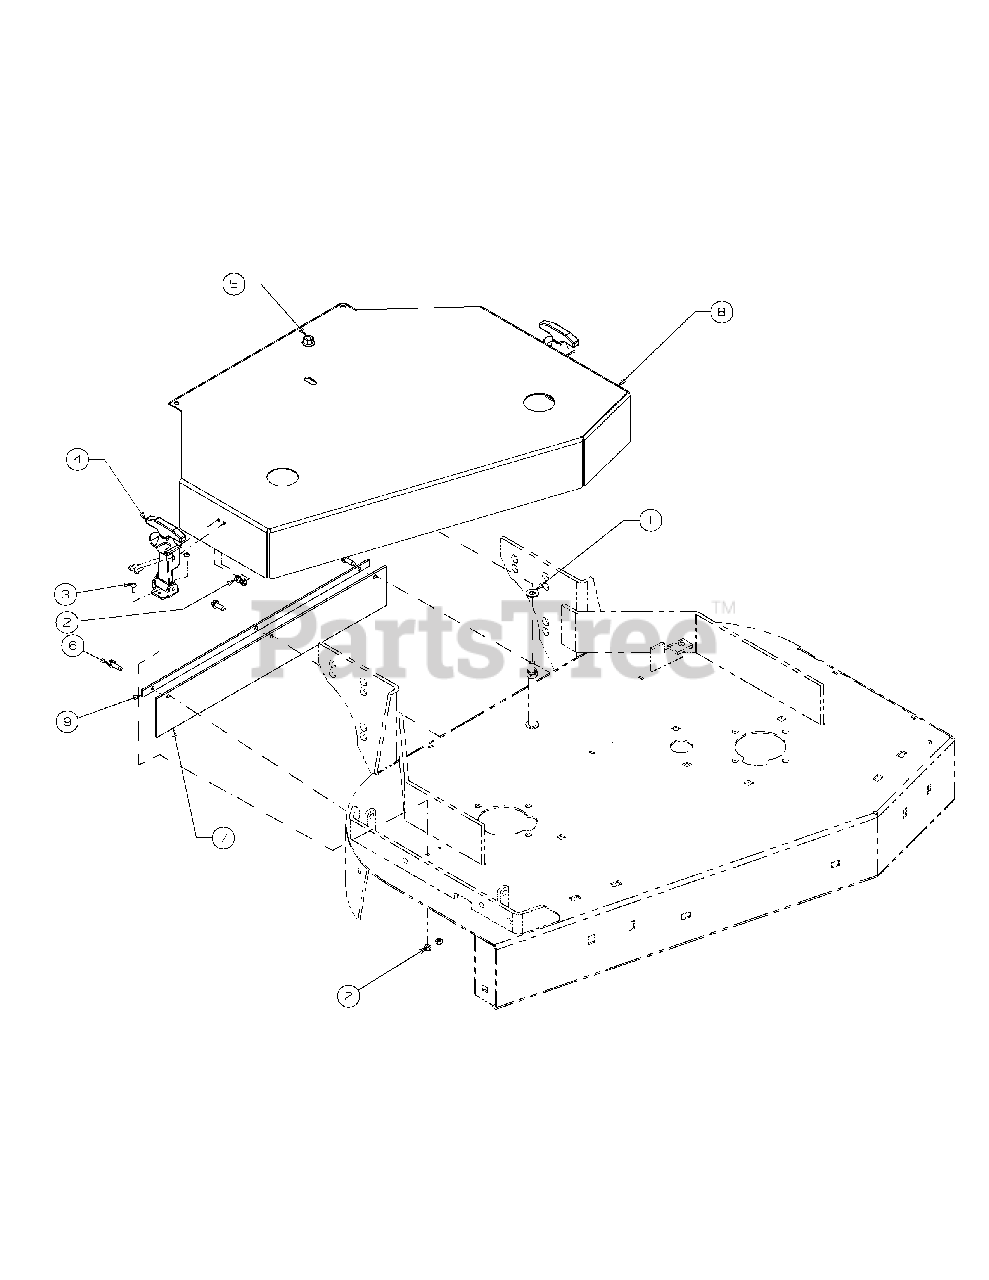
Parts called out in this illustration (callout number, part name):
1	Flat Washer, 3/8 Zinc
2	Lock Nut, Nylon Insert, 10-32
3	Phillips Head Screw, #10-32 x 1/2
4	Rubber Hood Latch
5	Hex Nut, 3/8-16, Flange Lock
6	Self Tapping Screw, 1/4-20 x 0.75
7	Trail Shield
